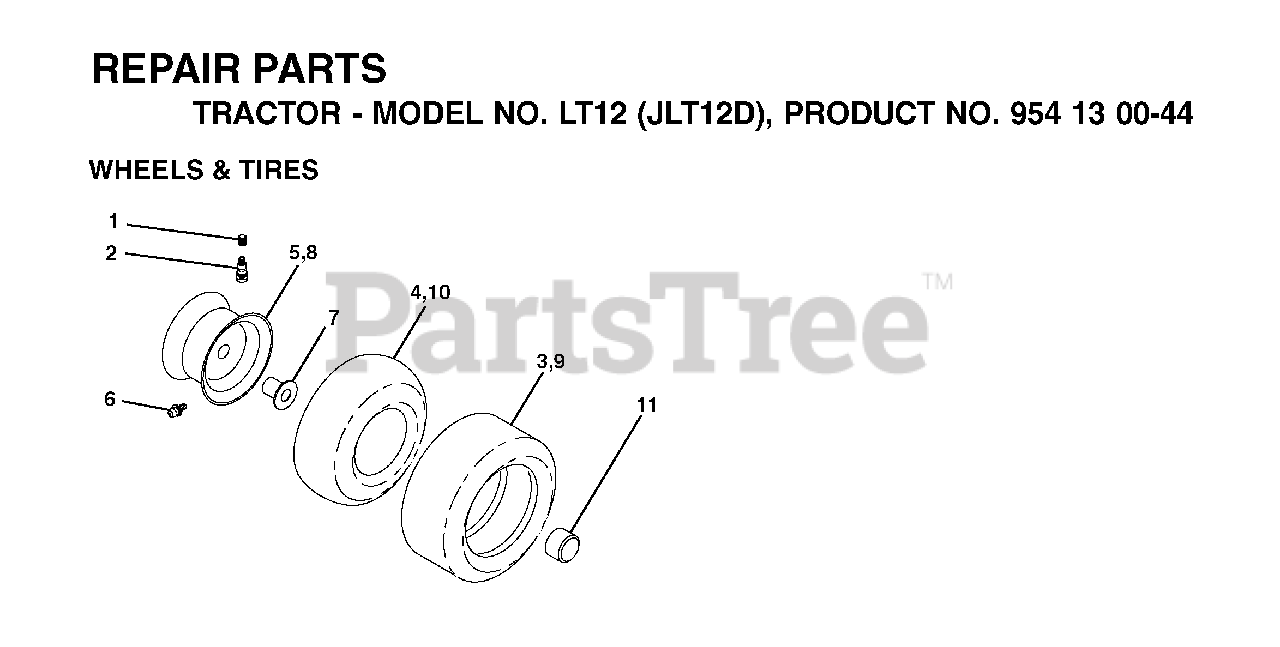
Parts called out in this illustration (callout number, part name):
1	VALVE CAP
2	VALVE STEM LT
3	TIRE HEAVY DUTY
4	TUBE.5.3/4.5/6
5	RIM ASM 6" FRONT SILVER
6	FITTING LT
7	BEARING T
8	RIM ASM 8" REAR SILVER
9	TIRE
10	TUBE
11	CAP, AXLE BLK
